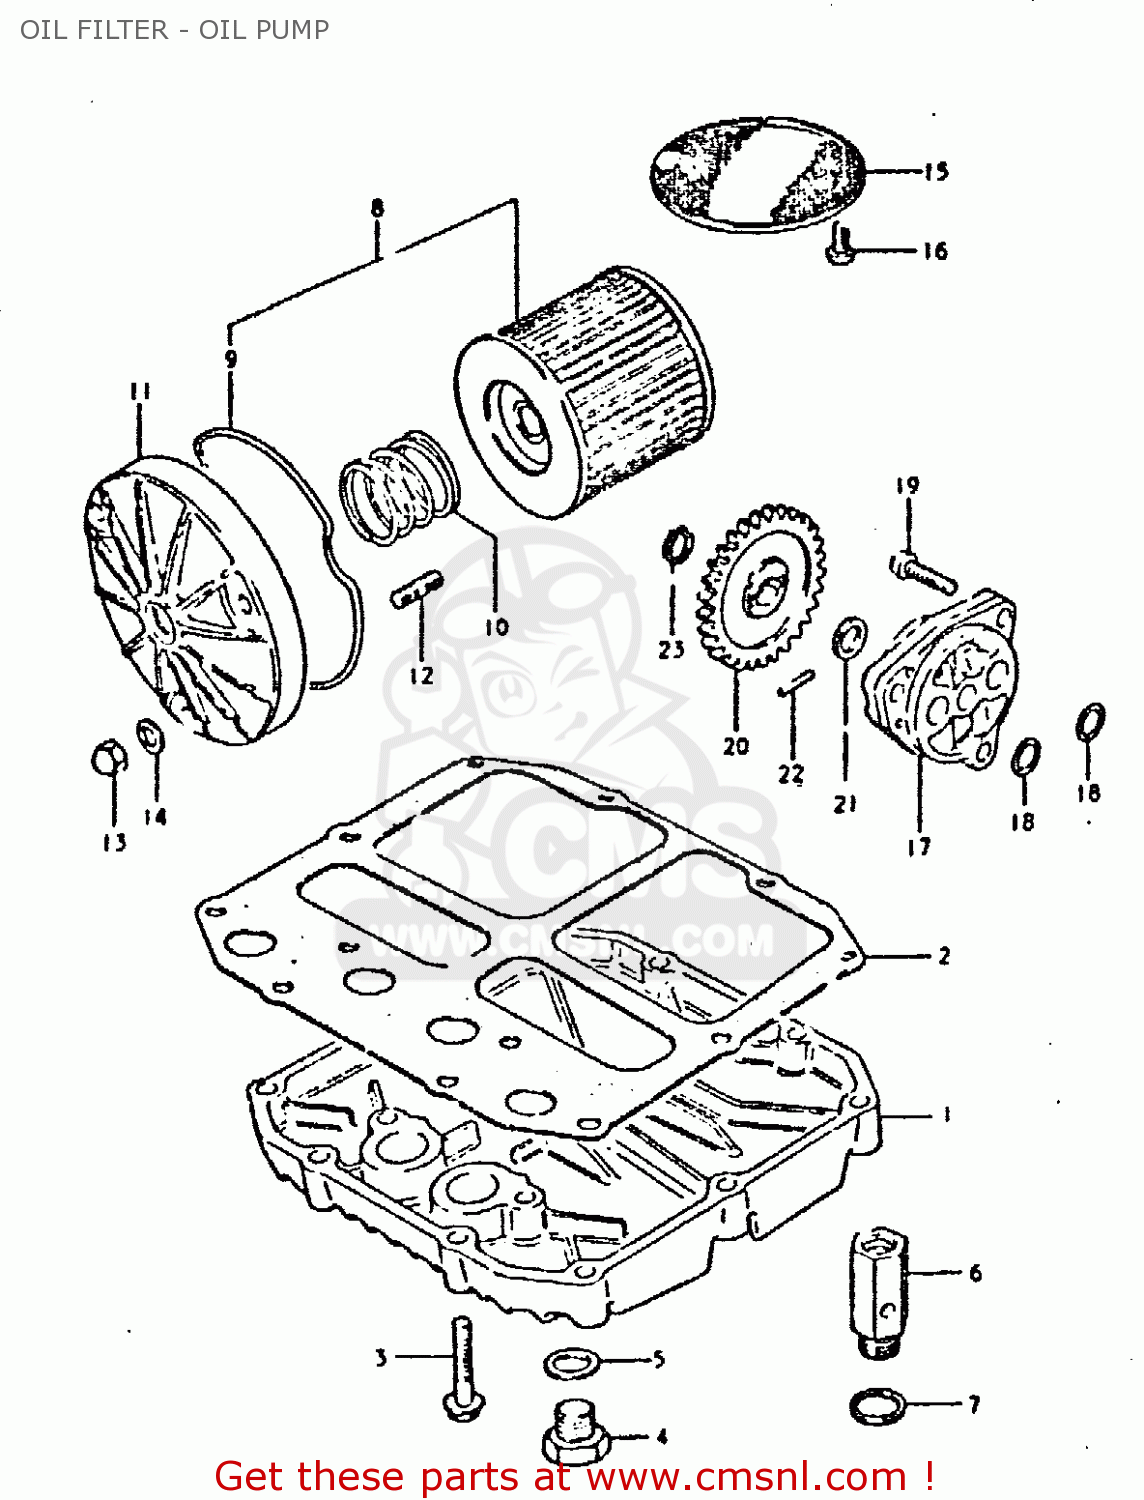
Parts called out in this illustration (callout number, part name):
1	PAN,OIL
2	GASKET,OIL PAN (MCA)
3	BOLT
4	PLUG
5	GASKET(14X19.2X2) (NAS)
6	REGULATOR ASSEMBLY,ENGINE
7	WASHER
8	ENGINE OIL FILTER SET
9	O RING,OIL FILTER CHAMBER CAP
10	SPRING
11	CAP,OIL FILTER
12	STUD 6X20
13	NUT
14	WASHER
15	STRAINER,ENGINE OIL
16	SCREW 6X12
17	PUMP ASSY,ENGINE OIL
18	O RING(D:1.9,ID:13)
19	SCREW
20	GEAR,OIL PUMP DRIVEN
21	SHIM
22	PIN(4X15.8)
23	CIRCLIP
